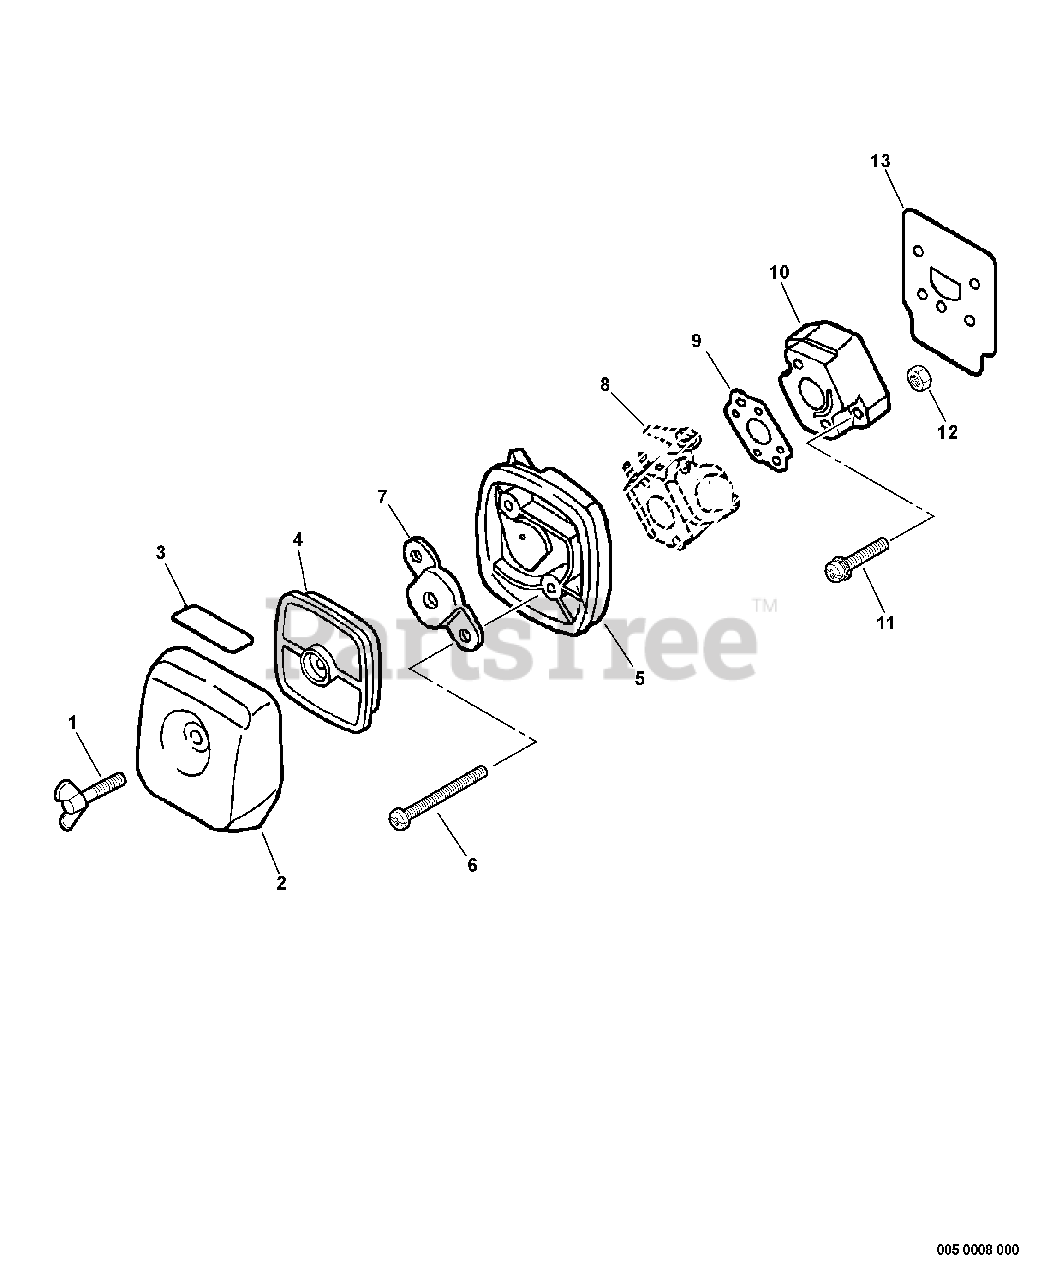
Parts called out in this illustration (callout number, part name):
1	BOLT, WING 5×20
2	COVER, AIR FILTER - GRAY
3	LABEL, CHOKE
4	FILTER, AIR - SINGLE LAYER
5	CASE, AIR FILTER - GRAY
6	SCREW 5×65
7	PLATE, PREVENT
8	CARBURETOR
9	GASKET, INTAKE
10	INSULATOR, INTAKE
11	SCREW 5×20
12	NUT M5
13	HEAT SHIELD, INTAKE
